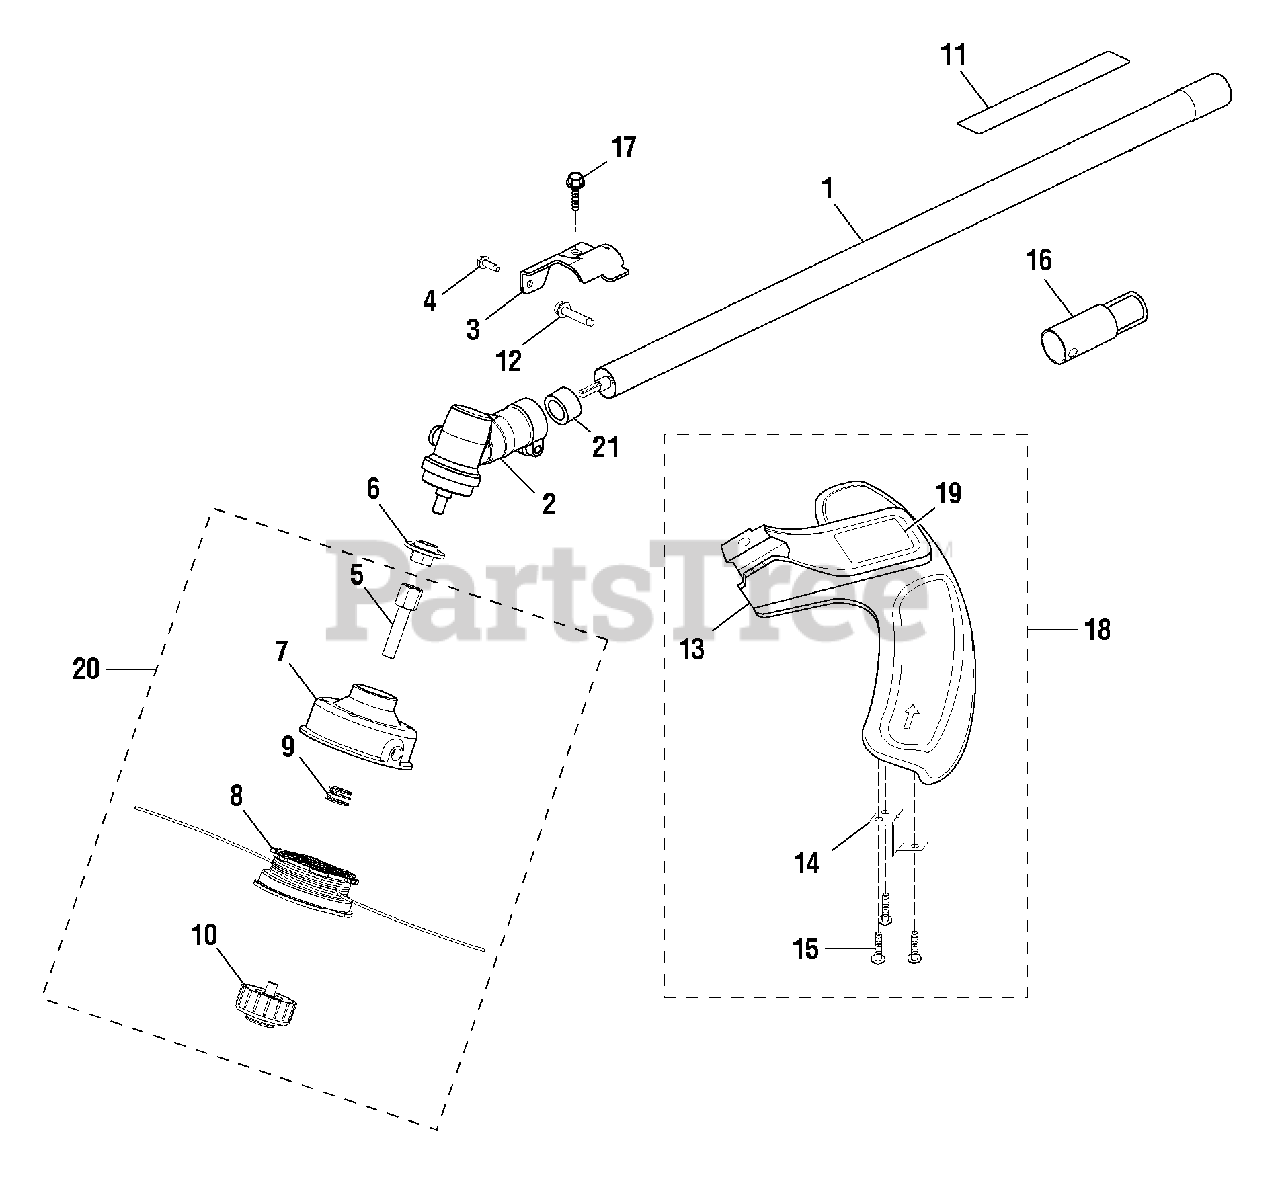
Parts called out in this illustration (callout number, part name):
1	STRAIGHT SHAFT ASSEMBLY
2	GEAR CASE ASSEMBLY
3	GRASS DEFLECTOR CLAMP
4	SCREW (#10-24 X 5/8 in. HEX WASHER HD.)
5	TRIMMER HEAD SHAFT ADAPTOR
6	FLANGED WASHER
7	TRIMMER HEAD
8	SPOOL WITH LINE (.095)
9	COMPRESSION SPRING
10	RETAINING CAP, LEFT-HANDED THREAD
11	WARNING LABEL
13	GRASS DEFLECTOR
14	LINE CUTTING BLADE
16	HANGER CAP
17	SCREW (#1/4-20 X 1-1/4 in. HEX WASHER HD.)
18	GRASS DEFLECTOR ASSEMBLY
19	GRASS DEFLECTOR LABEL
20	TRIMMER HEAD ASSEMBLY
21	SPACER
